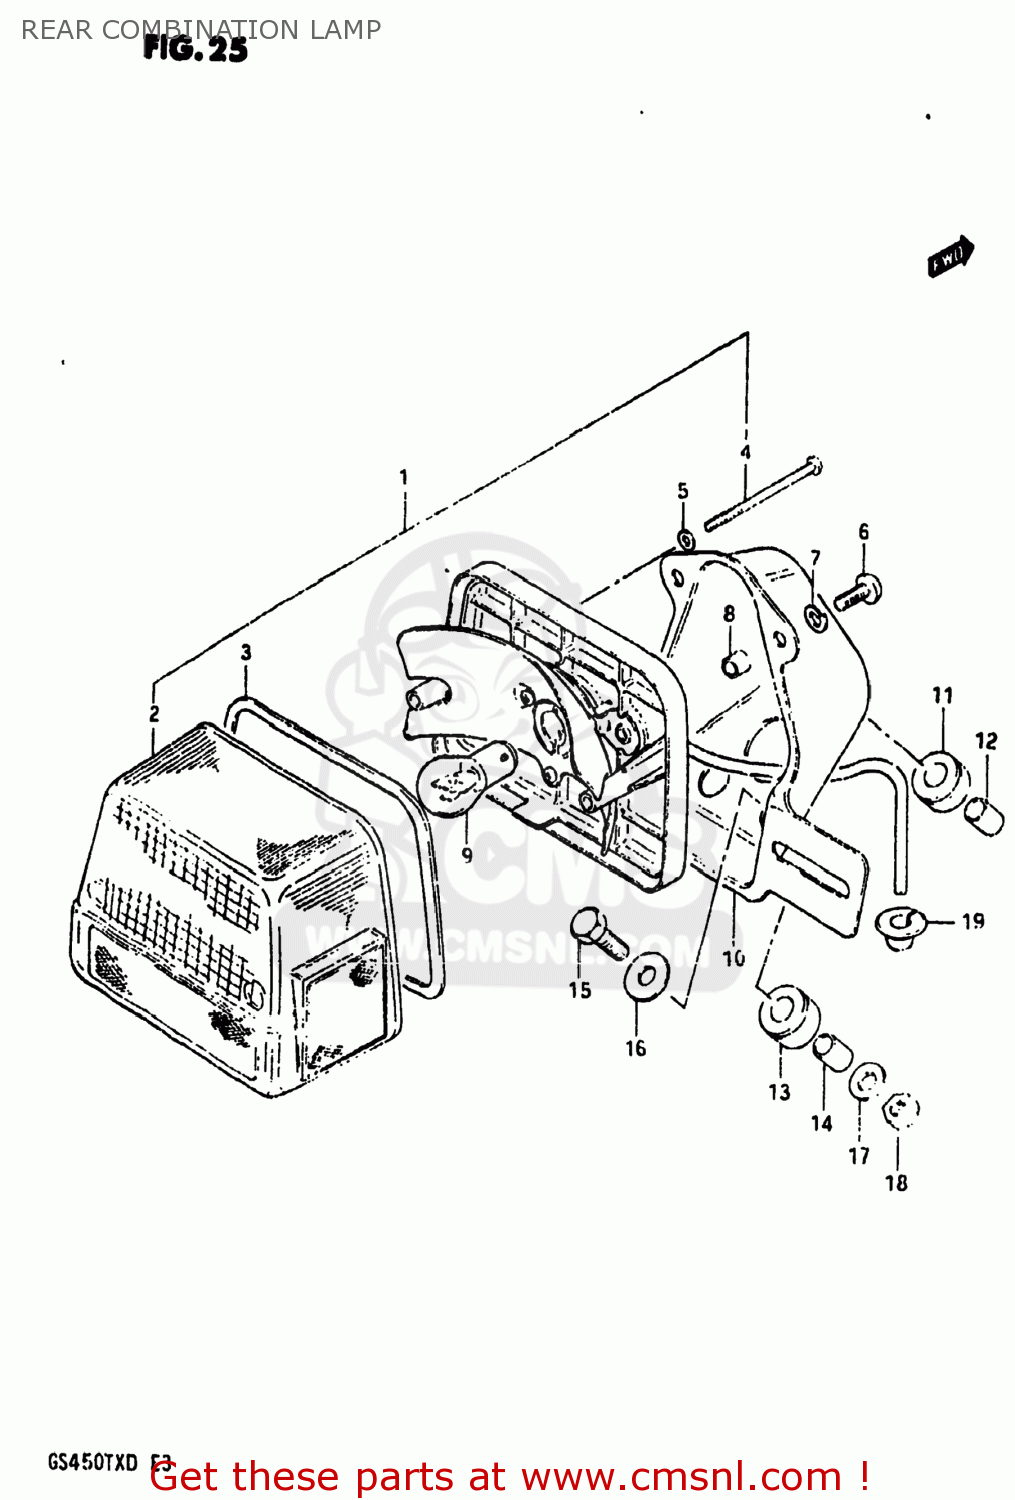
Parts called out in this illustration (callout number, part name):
1	LAMP UNIT,RR COMBNATION
2	LENS
3	GASKET (NAS)
4	SCREW
5	GASKET (NAS)
6	SCREW
7	LOCK WASHER
8	SPACER
9	BULB(12V23W)
10	BRACKET,REAR COMBINATION LAMP
11	CUSHION
12	SPACER
13	CUSHION,REAR COMBINATION LAMP
14	SPACER,REAR COMBINATION LAMP
15	BOLT
16	WASHER (6.5X20X1.2)
17	WASHER
18	NUT
19	GROMMET
